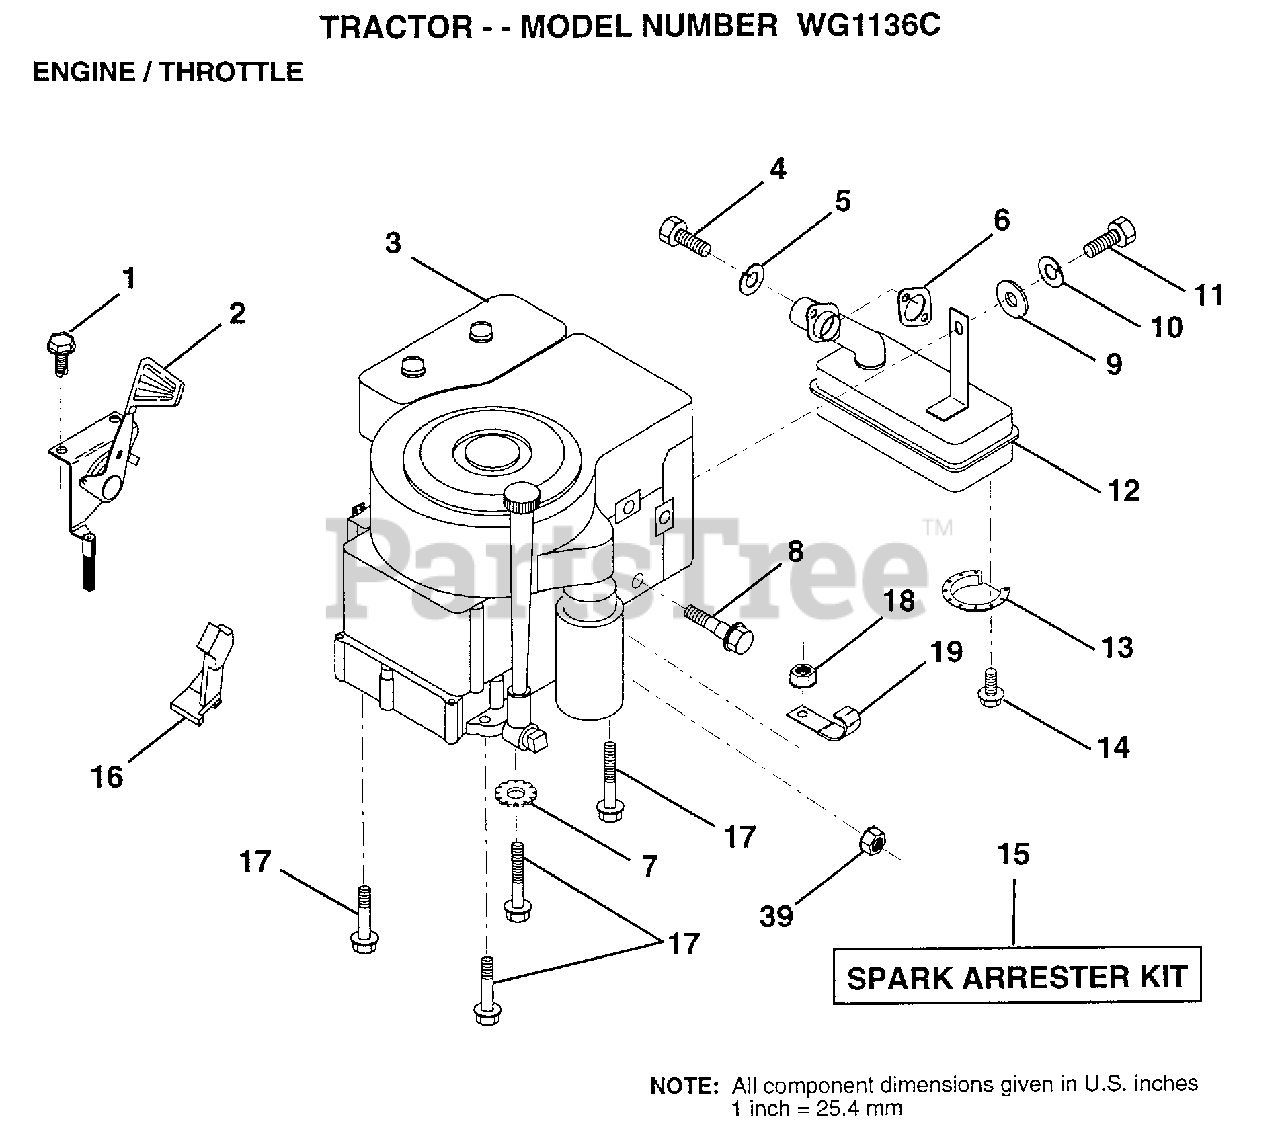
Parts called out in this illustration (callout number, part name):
1	SCREW.1/4-20X1/2
3	ENG B&S 10-12.5HP PWRBLT DC
4	SCREW
5	LOCKWASHER
6	GASKET ENG 1 313 LD TIN PLATED
7	LOCKWASHER
8	BOLT T
10	LOCKWASHER
12	MUFFLER
13	DEFLECTOR.222573
16	"STOP,DASH THROTT"
17	SCREW LT
18	NUT
19	CLIP T
39	NUT
